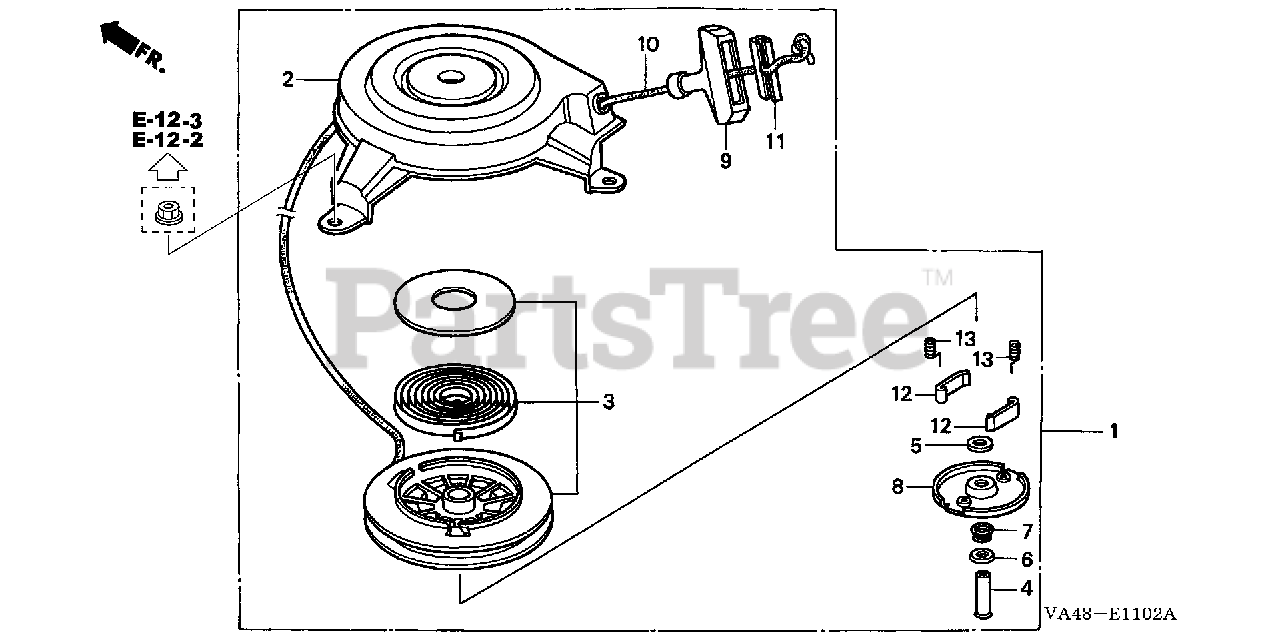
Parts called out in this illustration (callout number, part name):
1	STARTER ASSY., RECOIL
2	HOUSING ASSY. (NA USE ALT:28400-ZG9-803)
3	PULLEY & SPRING ASSY.
4	PIN, CENTER
5	PLATE A, FRICTION
6	PLATE B, FRICTION (NOT AVAILABLE)
7	SPRING, FRICTION
10	ROPE (#5.5X92")
11	HANDLE, REINFORCEMENT
12	RATCHET, STARTER
13	SPRING, DOG
